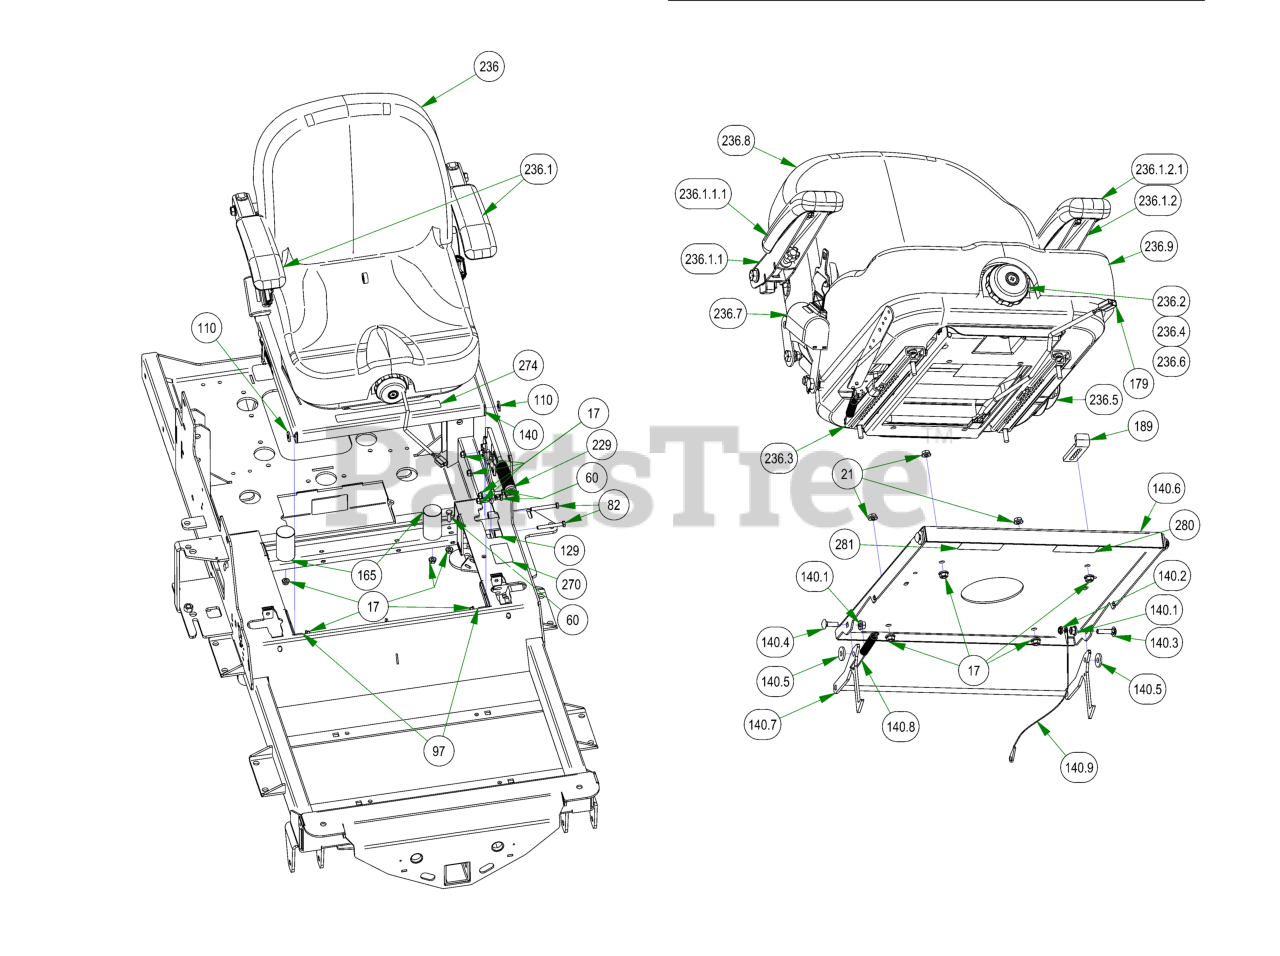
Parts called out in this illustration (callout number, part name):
17	5/16-18 NYLON INSERT FLANGE LOCKNUT ZINC
21	5/16-18 HEX SERRATED FLANGE NUT HARD/ZINC
60	5/16-18 X 1 HEX CAP SCREW (GR.5) ZINC
82	5/16-18 X 2-1/2 HEX CAP SCREW (GR.5) ZINC
97	5/16-18 X 1 CARRIAGE BOLT (GR.8) ZINC
110	.360 ID X .983 OD X .120 THICK FLAT WASHER NYLON
129	.380 ID X .625 OD X 1.500 LGTH 2019 OUTLAW BRAKE HANDLE SPACER ZINC
140	R-SERIES SEAT PLATE ASSEMBLY
140.1	5/16-18 NYLON INSERT FLANGE LOCKNUT ZINC
140.2	5/16-18 NYLON INSERT JAM LOCKNUT ZINC
140.3	5/16-18 X 1-1/4 CARRIAGE BOLT ZINC
140.4	5/16-18 X 1 CARRIAGE BOLT (GR.8) ZINC
140.5	.360 ID X .983 OD X .120 THICK FLAT WASHER NYLON
140.6	R-SERIES SEAT PLATE
140.7	Seat Latch Rod Assembly
140.8	Brake Spring
140.9	Seat Cable
165	2019 Bad Boy X Cylindrical Seat Mount
179	Seat Switch Adapter
229	2019 Brake Handle Assembly
235	2022 Horizontal Diesel Frame
236	2022 Suspension Seat w/Seatbelt
236.1	Set of Armrests-SS Front Adj
236.1.1	RH Armrest-Selfskin Front Adj
236.1.1.1	Black Selfskin-Arm Pad Only
236.1.2	LH Armrest-Selfskin Front Adj
236.1.2.1	Black Selfskin-Arm Pad Only
236.2	Weight Adjust Indicator Knob Assy
236.3	4" Single Locking Track Kit
236.4	Delta Plunger Switch - N.O.
236.5	Recliner Adjustment Knob-New
236.6	Bellows w/Hardware
236.7	2" Retractable Belt Kit w/Spacers
236.8	Back Cover for I3M - Recl - Logos
236.9	Cushion Cover Kit for I3M-Logo
270	2018 Out/XP/Diesel Brake Decal
274	Outlaw Warning Decal
280	Control Adj. Control Rod Decal
281	Control Adj. Control Dampener Decal
